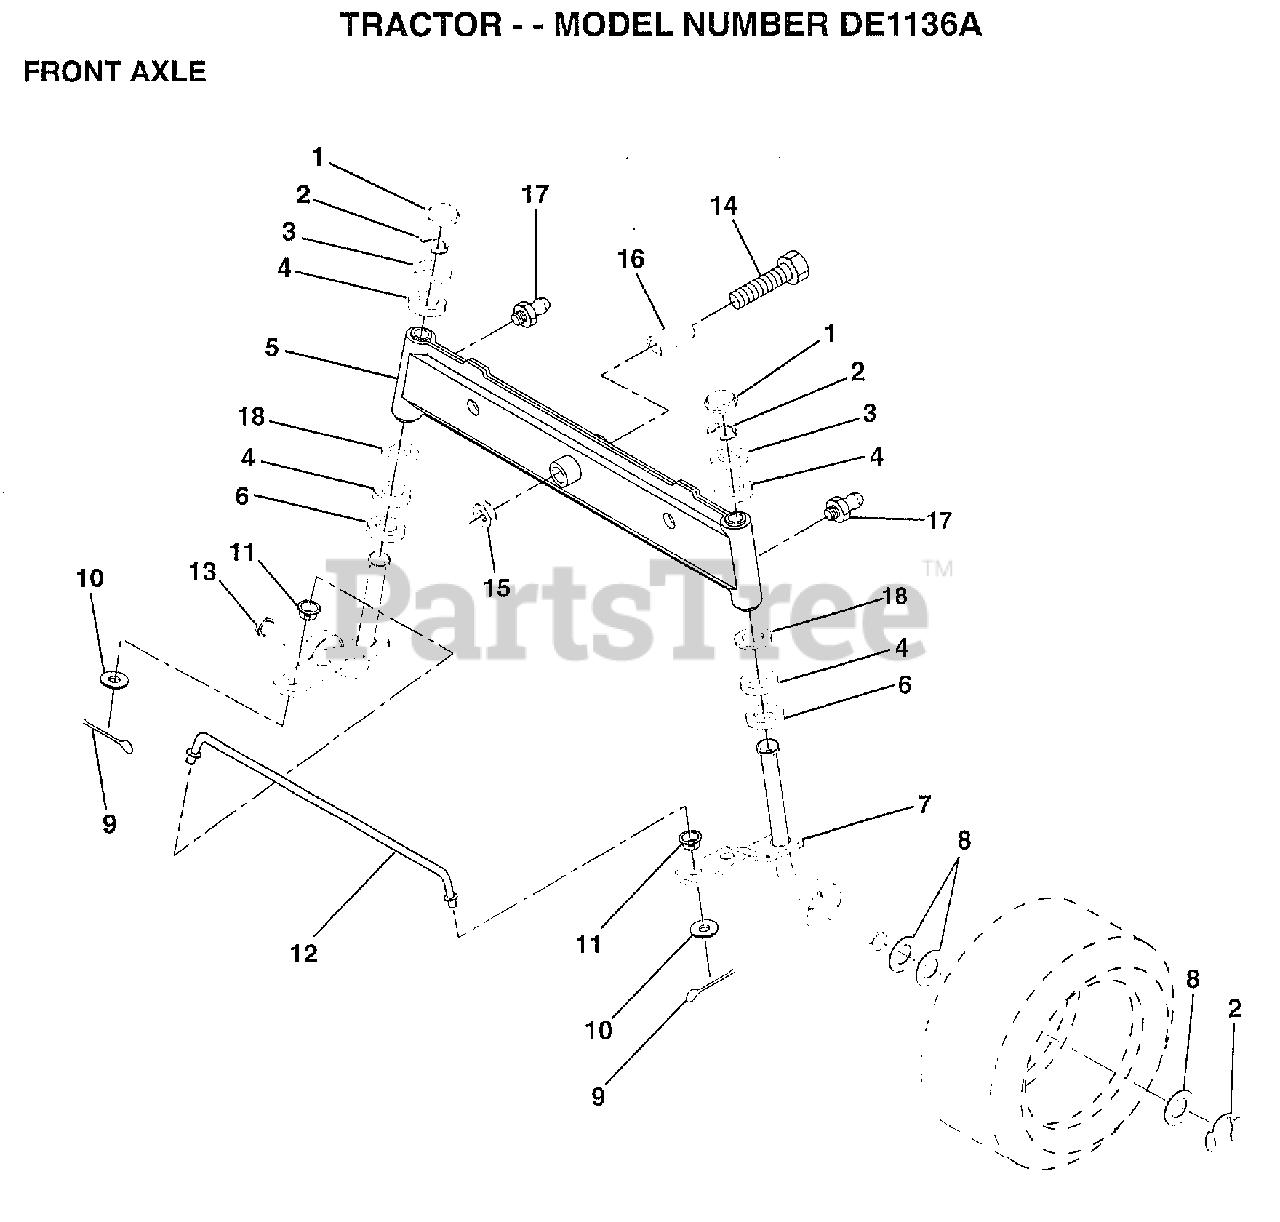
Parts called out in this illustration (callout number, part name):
1	CAP
2	RING
3	WASHER
4	COL. SRTG. BEAR.
5	AXLE ASM FRONT
6	WASHER .T
7	SPINDLE.ASSY.RH
8	WASHER
9	COTTER PIN
10	WASHER
11	BUSHING.DRAGLINK
12	TIE ROD
13	SPINDLE.ASSY.LH
14	BOLT HEX 5/8-11
15	"NUT-LOC,FLANGE LT"
16	BEARING
17	ZERK M
18	WASHER
